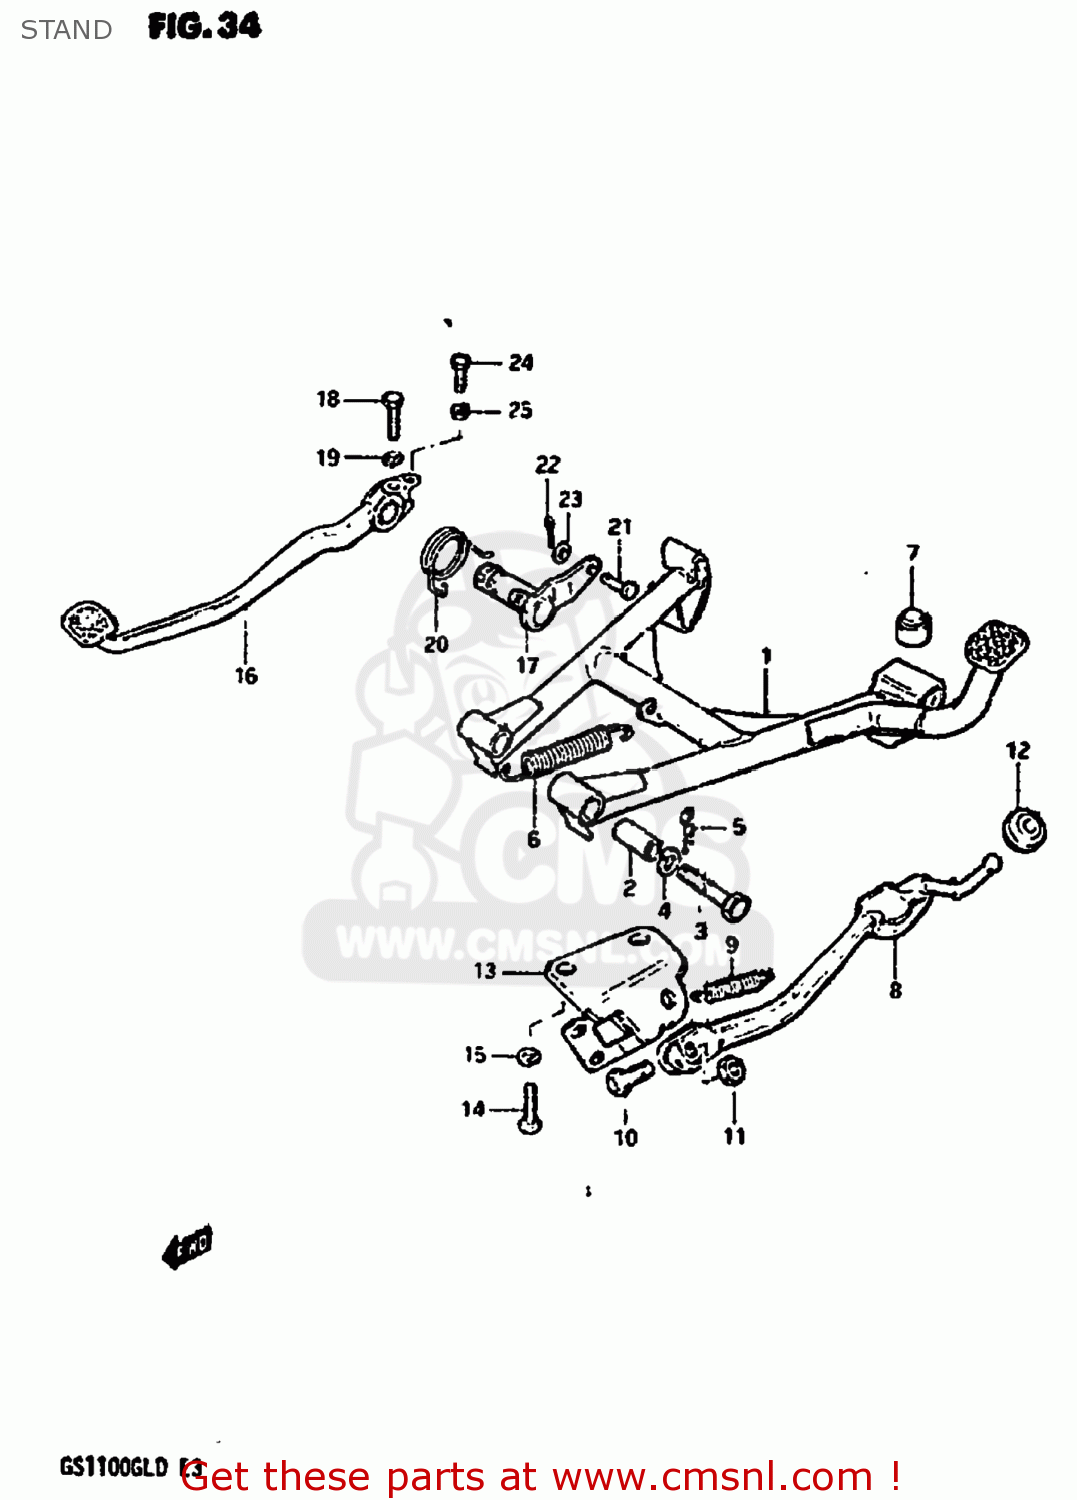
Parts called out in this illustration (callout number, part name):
1	STAND,CENTER
2	SPACER(10X16X38.8)
3	BOLT
4	LOCK WASHER
5	CLIP
6	SPRING
7	CUSHION
8	STAND,SIDE
9	SPRING
10	BOLT(10X30)
11	NUT
12	CUSHION
13	BRACKET,SIDE STAND
14	BOLT
15	LOCK WASHER
16	PEDAL,BRAKE
17	ARM,BRAKE PEDAL ROD
18	BOLT 8X50
19	LOCK WASHER
20	SPRING
21	PIN
22	PIN
23	WASHER
24	BOLT
25	NUT
